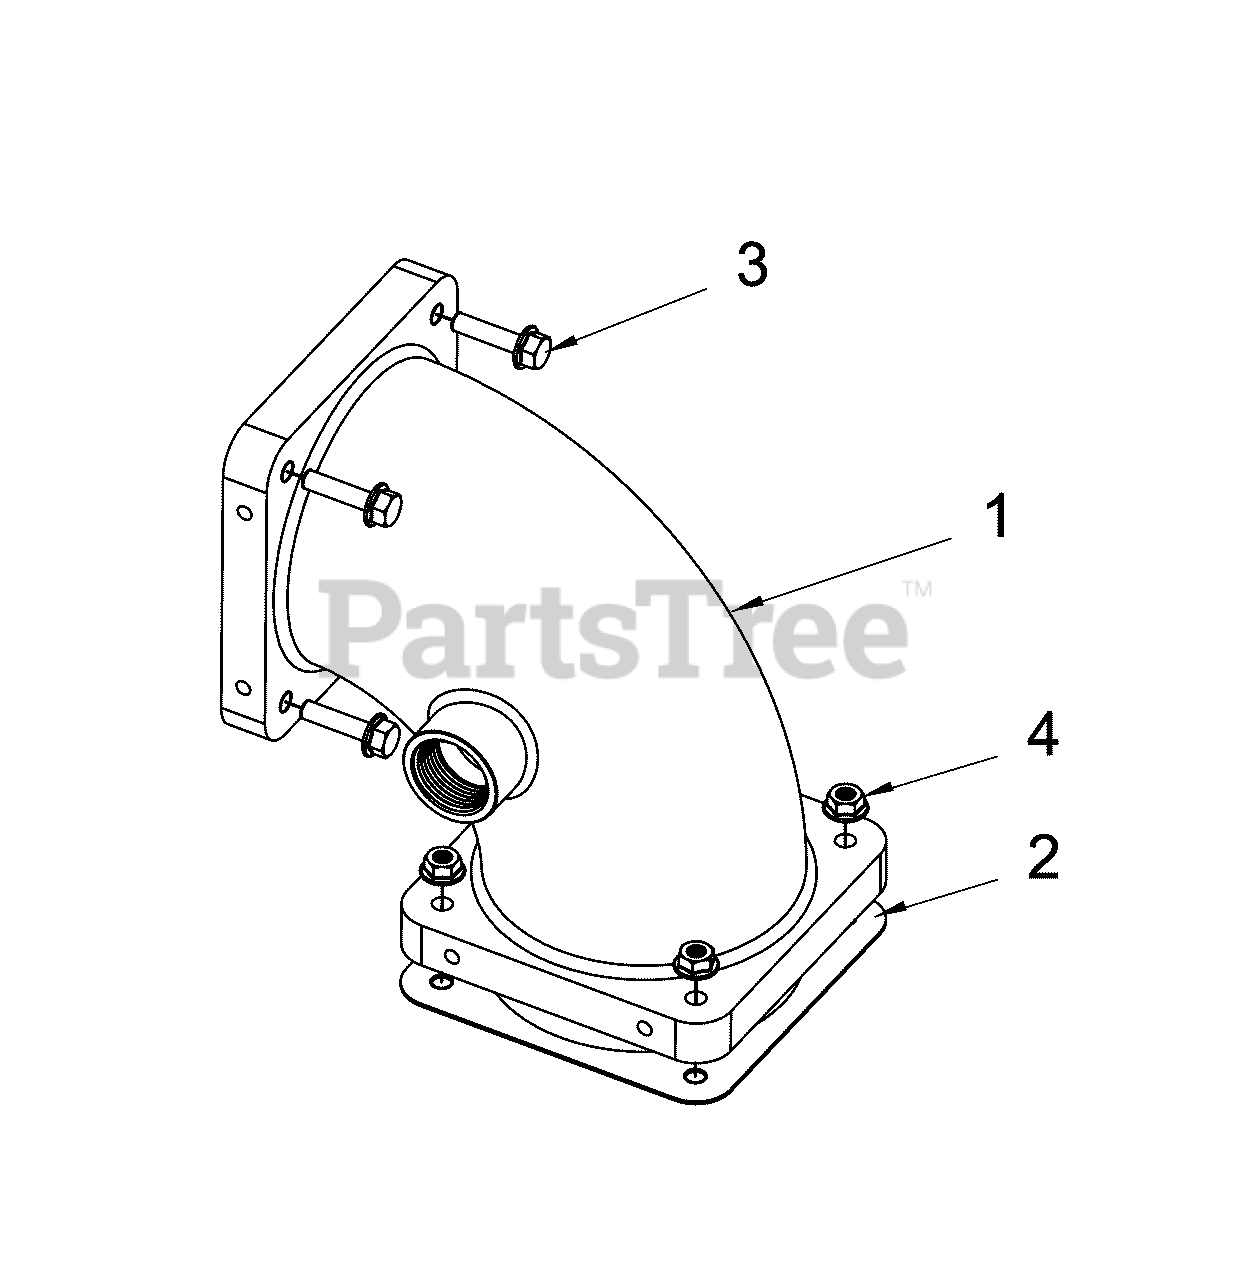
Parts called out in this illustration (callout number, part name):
1	* ADAPTER
2	* GASKET
3	* BOLT
4	* NUT
